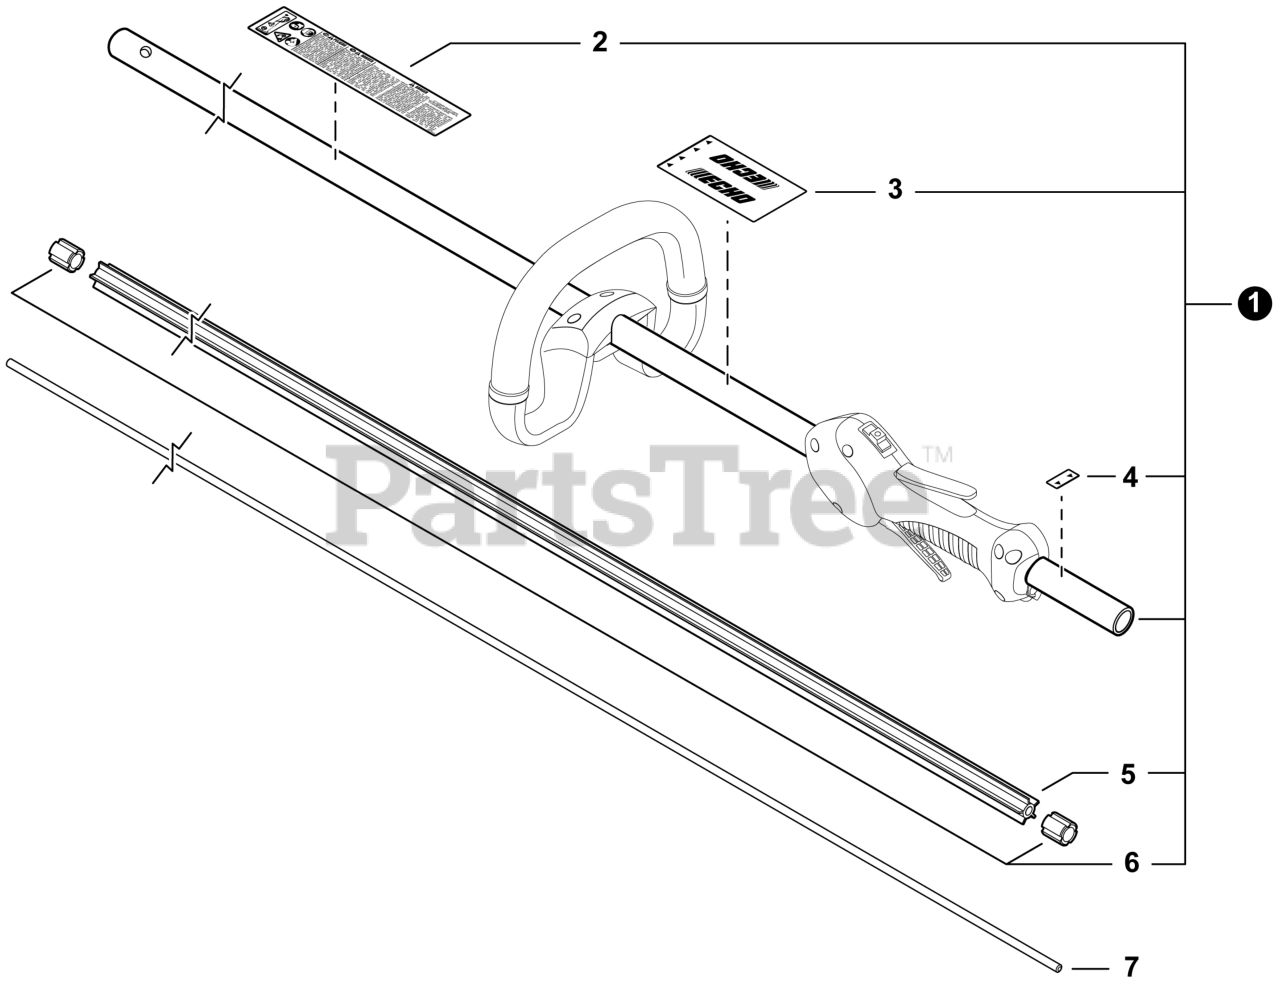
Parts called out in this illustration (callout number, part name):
1	MAIN PIPE ASSY
2	LABEL - CAUTION
3	LABEL - HANDLE LOCATION
4	LABEL - ALIGNMENT
5	LINER, FLEXIBLE 21.6×1420
7	DRIVESHAFT - FLEXIBLE
